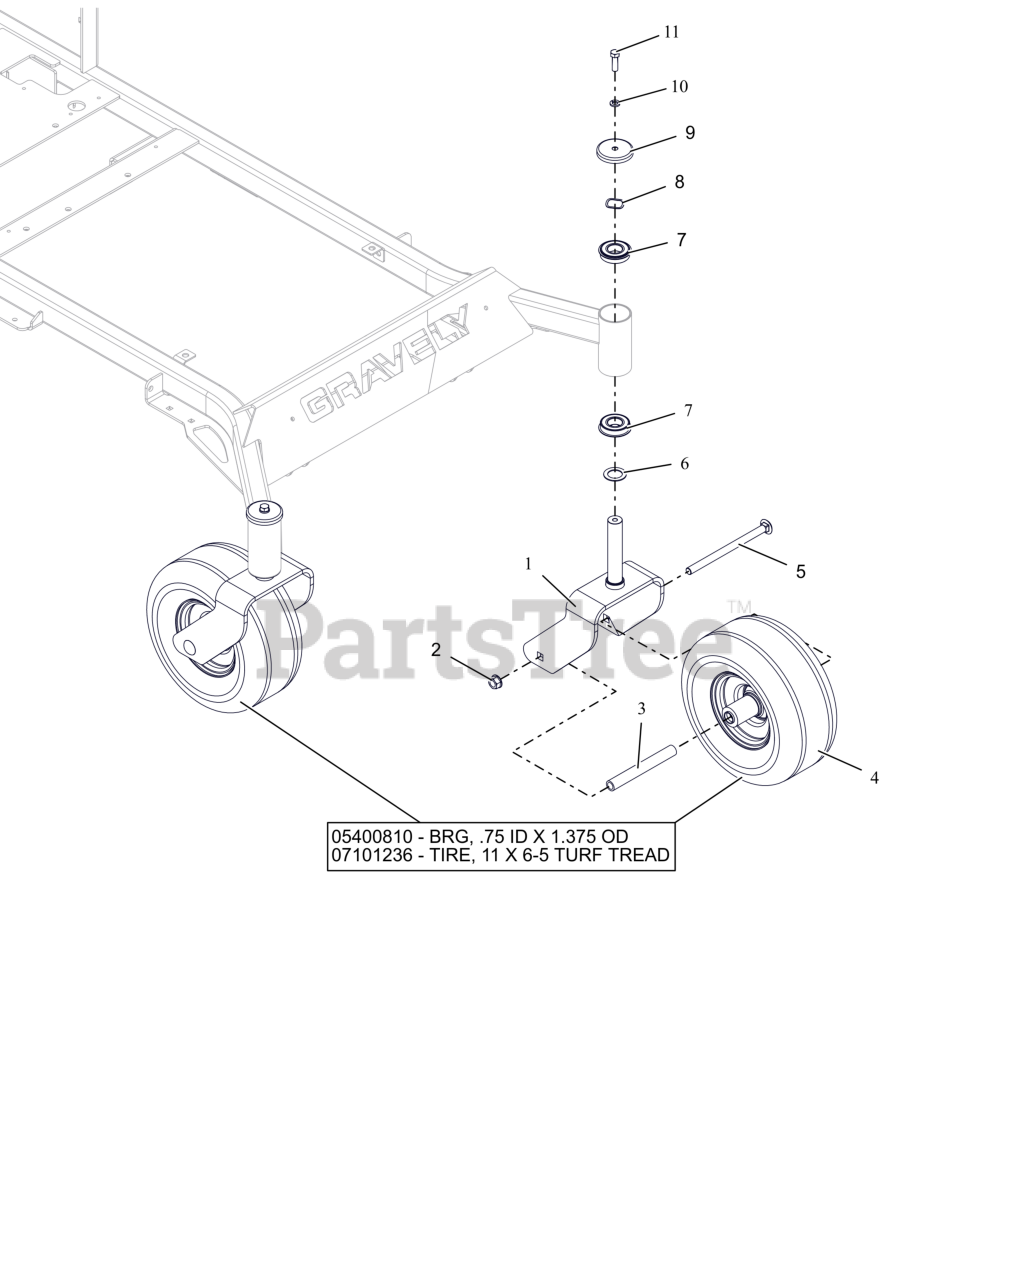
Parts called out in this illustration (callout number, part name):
1	WLDMT- CASTER FORK - RED
2	NUT-LK-CTR-FLG .500-13 GG ZCC
3	SPACER, FRONT WHEEL (WIDE 6.0)
4	ASM- WHL/TIRE 11X6-5
4	BRG, .75 ID X 1.375 OD
4	TIRE, 11X6-5 Smooth
5	BLT, RHSN .50-13X7.50 G5 ZCC
6	WSHR-HRD-THRS 1.007X1.542X.062
7	BEARING, BALL -2.000 OD X 1.000 ID X .5625 W/RING
8	WSHR-WAVE 1.0X1.25X.028 .145FH
9	SHIELD, AXLE BEARING
10	WSHR,LK-REG .375X.094 ZCC
11	BLT, HEX .38-16X1.25 G5 ZCC
